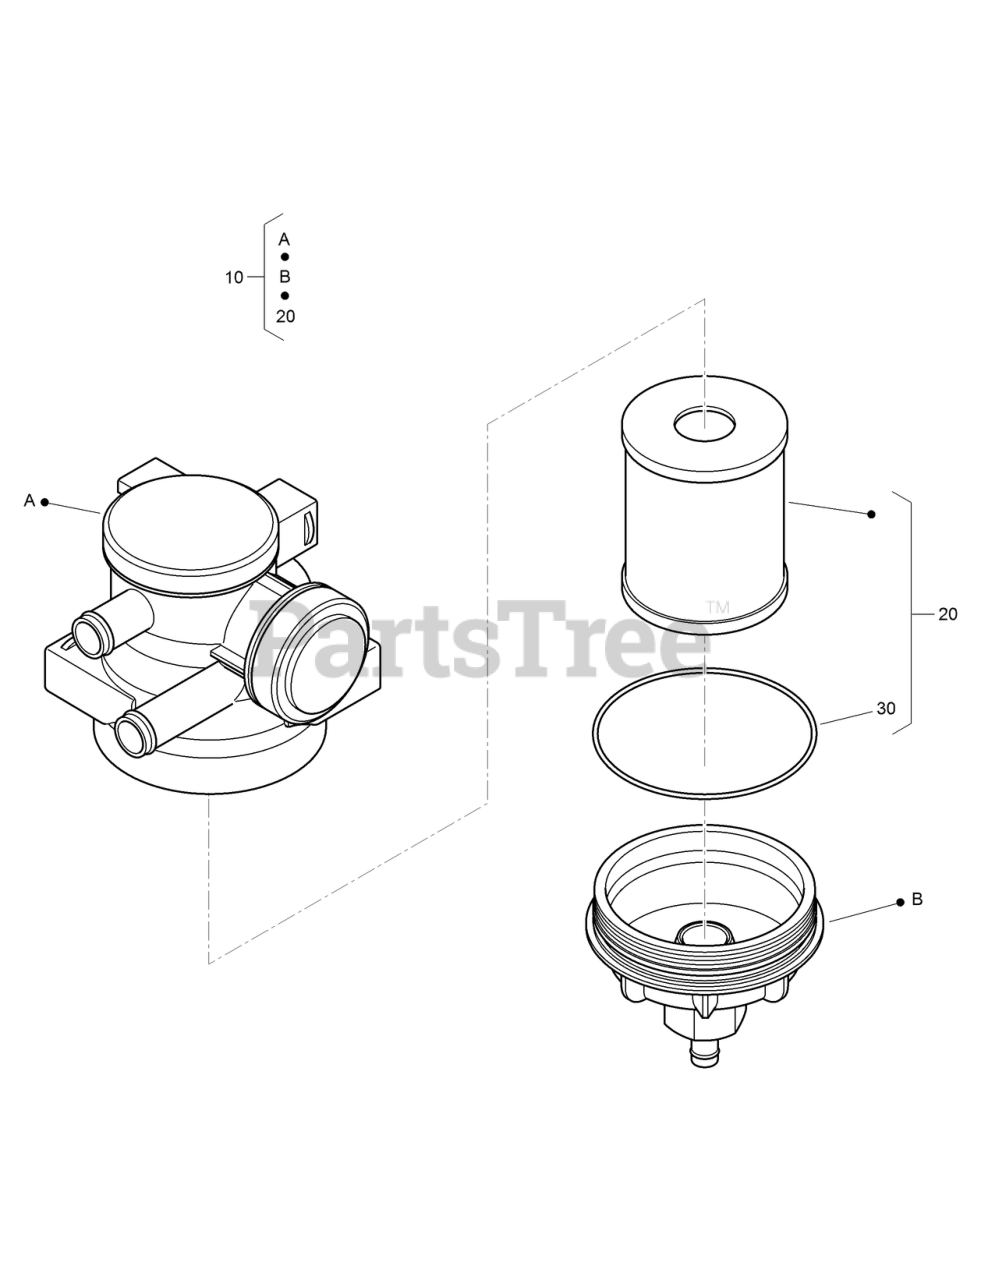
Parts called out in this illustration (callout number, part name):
10	SEPARATOR ASM
20	ELEMENT KIT
30	O-RING
